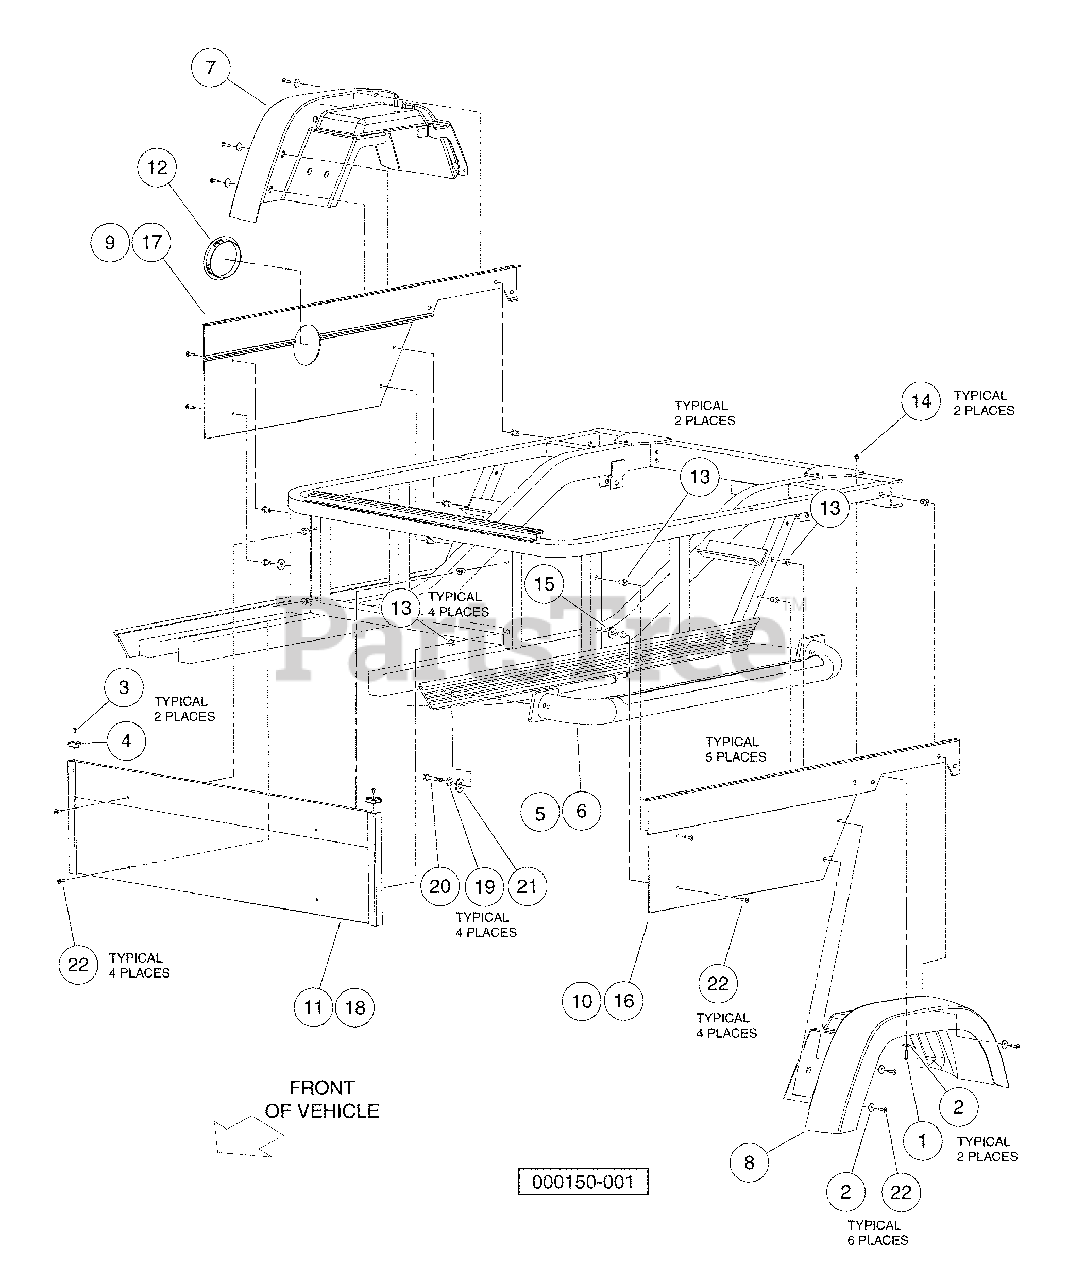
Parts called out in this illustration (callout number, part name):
1	Screw, M6-1.00 X 25mm Hex Cap
2	Washer, 1/4" Type B Flat
3	Screw, #10 Truss-Head Torx
4	Corner Cap AWD
5	Side Step Bar
6	Side Step Bar
7	Fender, Right Rear
8	Fender, Left Rear
9	Assembly, Panel
10	Assembly, Panel
11	Panel, Front
12	Bezel, Fuel Fill
13	Well Nut 1/4-20
14	Nut Flg, M6 X 1.0 Nylon
15	Washer, M12 Hard Regular
16	Panel, Side, Driver, Steel
17	Panel, Side, Passenger, Steel
18	Panel, Front, Steel
19	Washer, Lock, Hel Sp 3/8 Reg
20	Bolt, 3/8-16 X 3.00 Hex Head
21	Washer, 3/8 Type B Flat
22	Screw, 1/4-20 X 1.0 Truss-Head Machine
